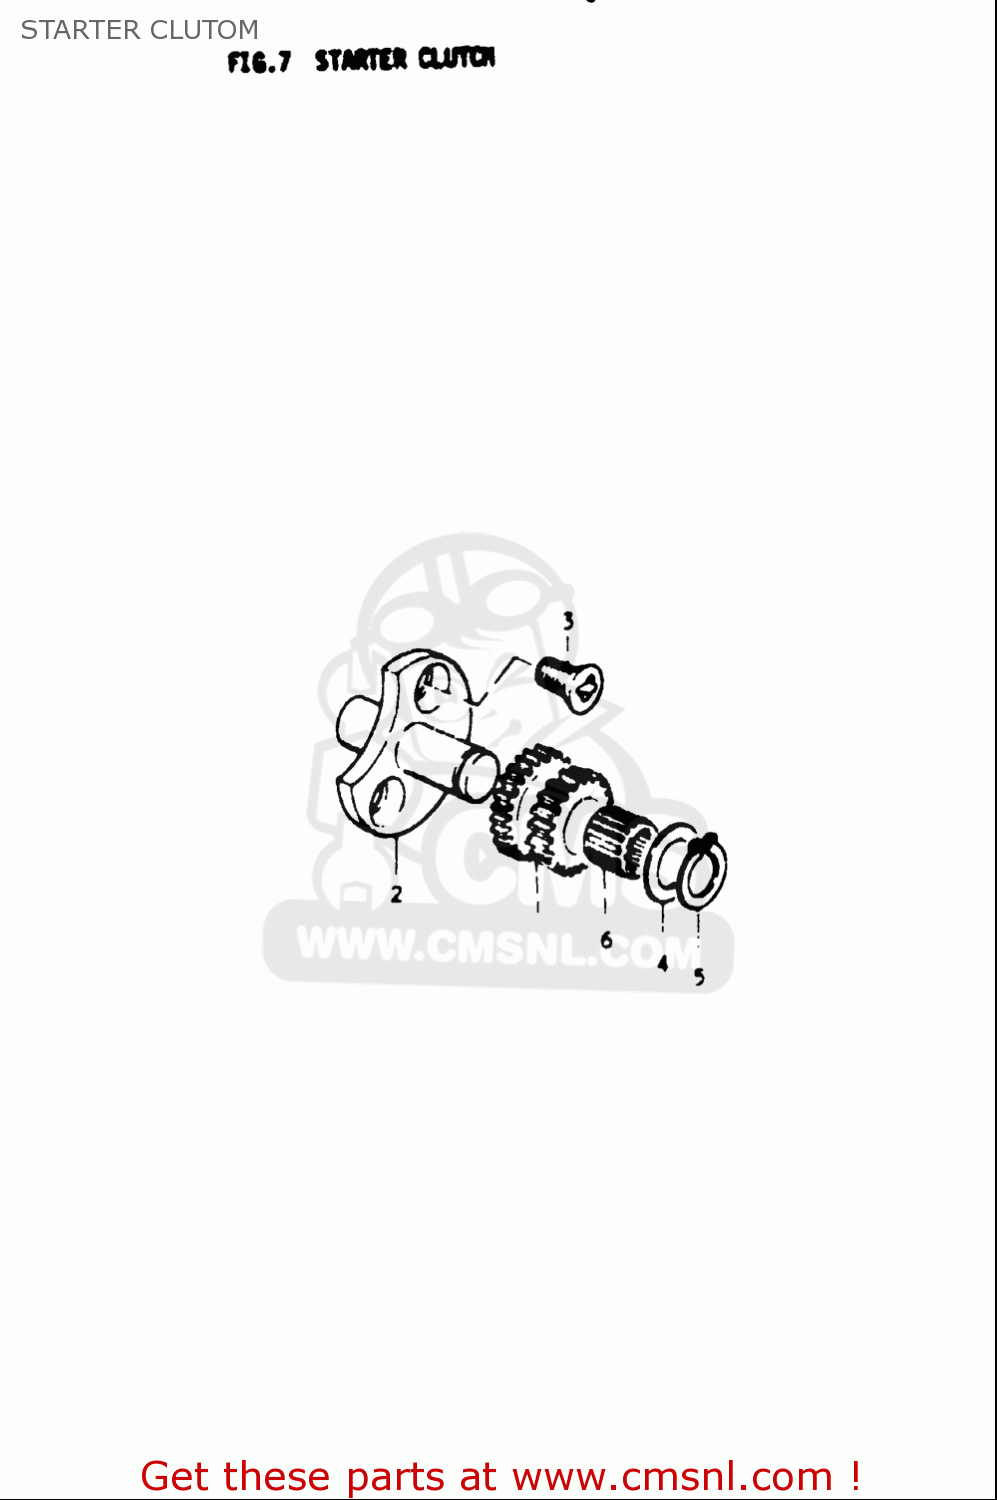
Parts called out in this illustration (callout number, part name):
3	SCREW
4	WASHER,THRUST
5	CIRCLIP,12 MM
